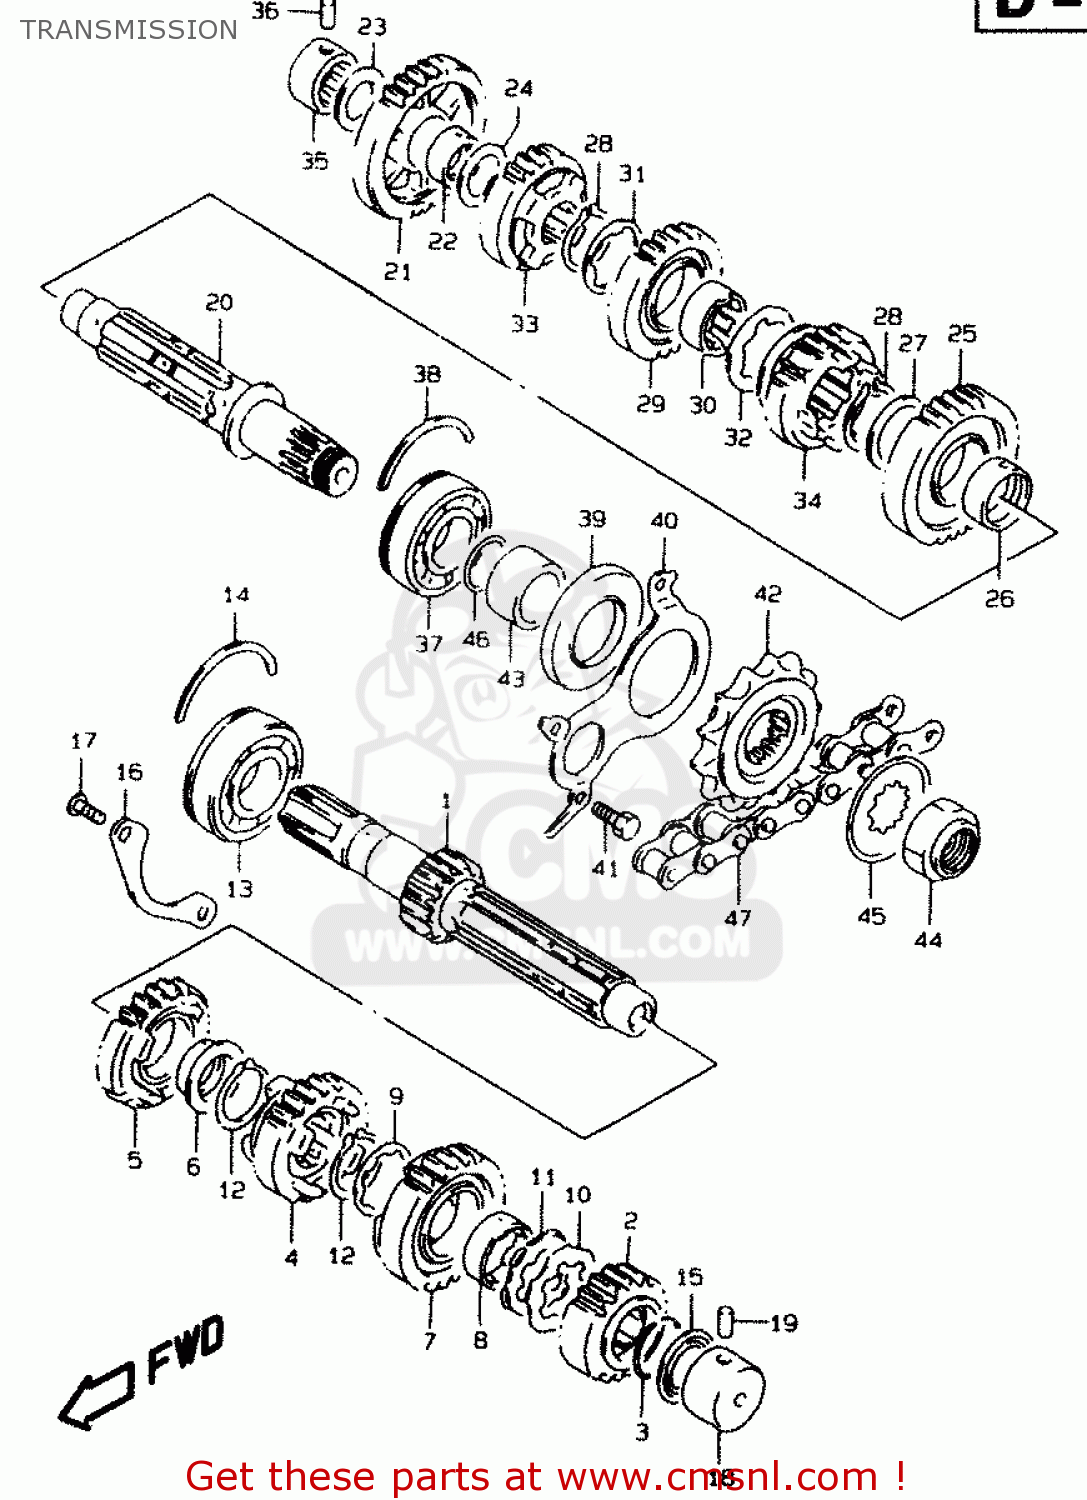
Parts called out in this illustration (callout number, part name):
1	SHAFT,COUNTER (NT:13)
2	GEAR,2ND DRIVE(NT:19)
3	CIRCLIP
4	GEAR,THIRD DRIVE (NT:20)
5	GEAR,FOURTH DRIVE (NT:22)
6	BUSHING
7	GEAR,FIFTH DRIVE (NT:23)
8	BUSH,5TH DRIVE GEAR
9	WASHER,LOCK
10	WASHER,LOCK
11	WASHER
12	RING,SNAP
13	BEARING(25X62X17)
14	C RING
15	SEAL,OIL(20X31.2X2.7)
16	RETAINER,CNTR SHAFT BEARING
17	SCREW
18	BEARING(20X34X17.5)
19	PIN
20	SHAFT,DRIVE
21	GEAR,FIRST DRIVEN (NT:31)
22	BUSHING
23	WASHER
24	WASHER
25	GEAR,2ND DRIVEN(NT:31)
26	BUSH(28X32X11)
27	WASHER
28	CIRCLIP
29	GEAR,THIRD DRIVEN (NT:25)
30	BUSH,3RD DRIVEN GEAR
31	WASHER,LOCK
32	WASHER,LOCK
33	GEAR,FOURTH DRIVEN (NT:23)
34	GEAR,FIFTH DRIVEN (NT:21)
35	BEARING(20X34X20)
36	PIN
37	BEARING(25X62X21.6)
38	C RING
39	SEAL,OIL(34X62X6)
40	RETAINER,DRIVE SHAFT OIL SEAL
41	BOLT
42	SPROCKET,ENGINE(NT:15)
43	SPACER(25X34X19)
44	NUT
45	WASHER,LOCK
46	O RING(D:1,ID:24.5)
47	CHAIN ASSEMBLY,DRIVE RKGB5
